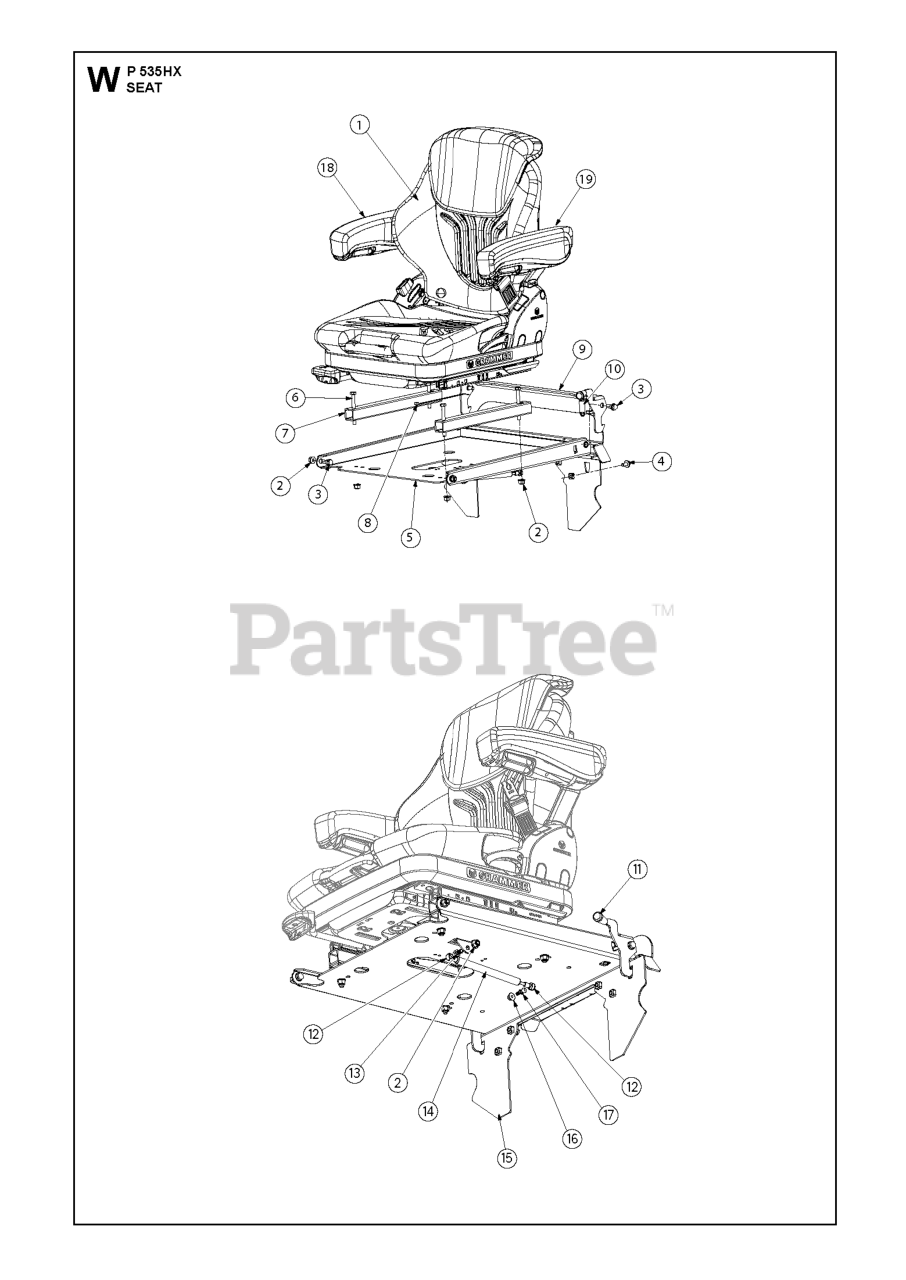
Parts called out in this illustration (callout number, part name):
2	NUT FLANGE
10	DRAW SPRING L=50
16	NUT FLANGE
